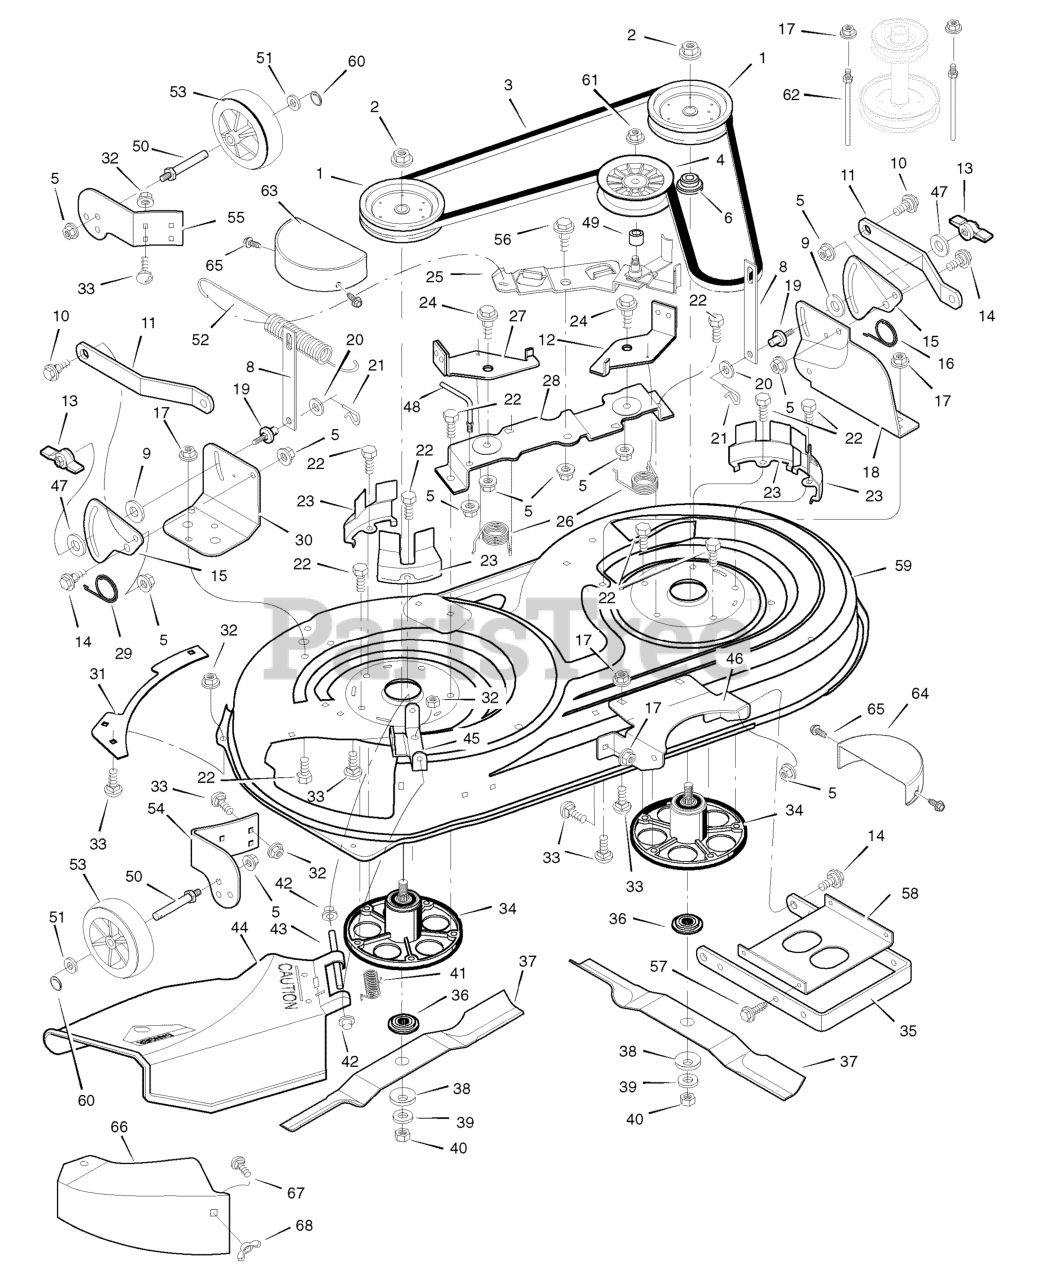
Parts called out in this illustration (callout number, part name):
1	Pulley, Jackshaft
2	Nut, Hex
3	Belt, Mower Drive
4	Pulley, Idler
5	Nut, Flange
6	SPACER, Pulley
8	Link, Lift
9	Pad, Friction
10	Bolt, Shoulder
11	Bracket, Suspension
12	Pad Assembly, Left Brake
13	Knob
14	Bolt, Shoulder
15	Plate, Suspension
17	Nut, Flange
18	Bracket, Suspension
19	Pin, Hanger
21	Pin, Hair
22	Bolt
23	Cover, Pulley
24	Bolt, Shoulder
25	Arm, Idler
27	Pad Assembly, Right Brake
28	Bracket, Brake
30	Bracket, Deck
32	Nut, Flange
33	Bolt, Carriage
34	Mandrell Housing
35	Bracket, Suspension
36	Adapter, Blade
37	Blade
42	Cap, Push On
43	ROD, Deflector
44	Deflector Assembly
45	Bracket, Deflector Hinge
46	Bracket, Front Hanger
48	Guide, Belt
50	BOLT, Gauge Wheel
52	Spring, Extension
53	Wheel, Gage
54	Bracket, Right Wheel
55	Bracket, Left Wheel
56	BOLT, Shoulder
59	Housing, Blade, Complete (NO LONGER AVAILABLE)
59	Housing, Blade (Housing Only)
60	Ring, Locking
61	Nut, Flange
62	Guide, Belt
63	GUARD, Pulley R.H.
64	GUARD, Belt L.H.
66	COVER, Mulch
67	Bolt, Carriage
68	WINGNUT
